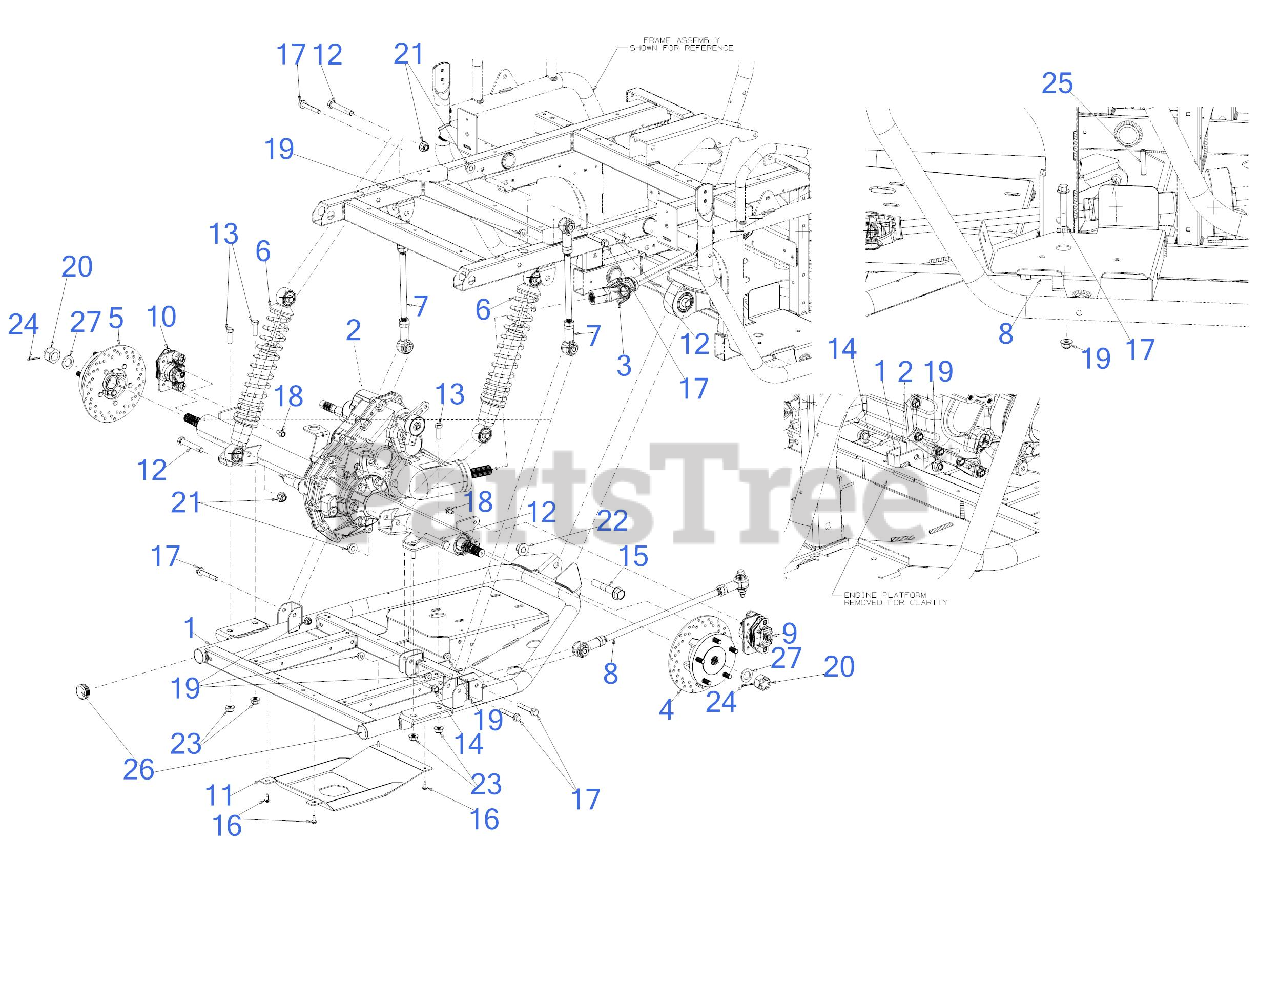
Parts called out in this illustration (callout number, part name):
2	TRANSMISSION ASSEMBLY 4X4
3	REAR DRIVE SHAFT ASSEMBLY
4	WHEEL HUB ASSEMBLY (RIGHT REAR)
4	DISK BRAKE (8.00X.188)
5	WHEEL HUB ASSEMBLY (LEFT REAR)
5	DISK BRAKE (8.00X.188)
6	SHOCK ABSORBER ASSEMBLY (REAR)
7	LOWER SWAY ROD ASSEMBLY
8	RADIAL ROD ASSEMBLY
9	FRONT BRAKE CALIPER ASSEMBLY (RH)
10	FRONT BRAKE CALIPER ASSEMBLY (LH)
11	TRANSMISSION SHIELD BRACKET
12	SCREW-HEX 1/2-13 X 3.00
13	HEX SCREW 7/16-14 x 1.25
14	SCREW 3/8-18 x 1.75 GR5
15	HEX FLANGE BOLT 5/8-11:3.75
16	SCREW M6-1 x .625
17	HEX FLANGE BOLT 5/16-16:2.5
18	FLANGE BOLT (1.25 x 16 x 8.8)
20	SLOTTED NUT22X1.5
22	FLANGE LOCK NUT
23	HEX FLANGE LOCK NUT 7/16-14
24	COTTER PIN
25	ROLL PIN (5/16-1.75)
26	BUMPER CAP
27	THRUST WASHER
